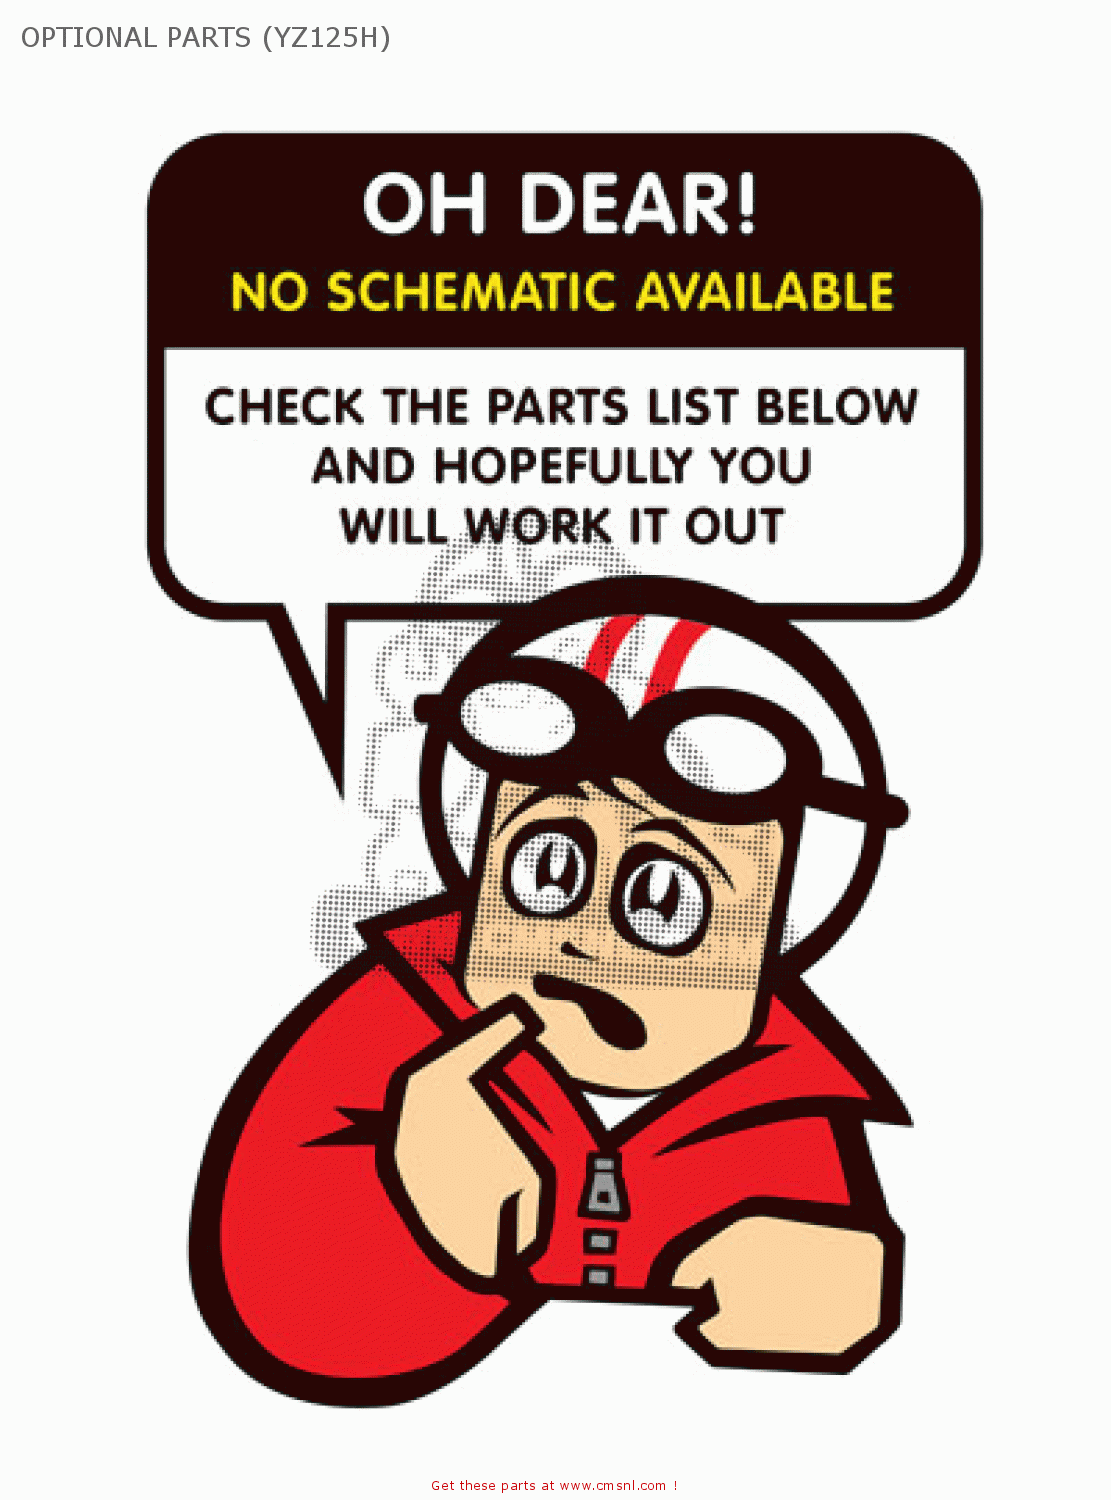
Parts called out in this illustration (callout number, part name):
1	GASKET,TIMING COV (NAS)
2	SEAL VALVE STEM
3	GASKET,CYLN HEAD (NAS)
4	GASKET,HEAD COVER (NAS)
5	GASKET,CAM REDUC (NAS)
6	PKG, OIL FILLER (NAS)
7	GASKET,EX.PIPE (NAS)
8	PACKING,MUFFLER (NAS)
9	PACKING,MUFFLER (NAS)
10	GASKET,AIR FEED P (NAS)
11	RUBBER,MOUNT
